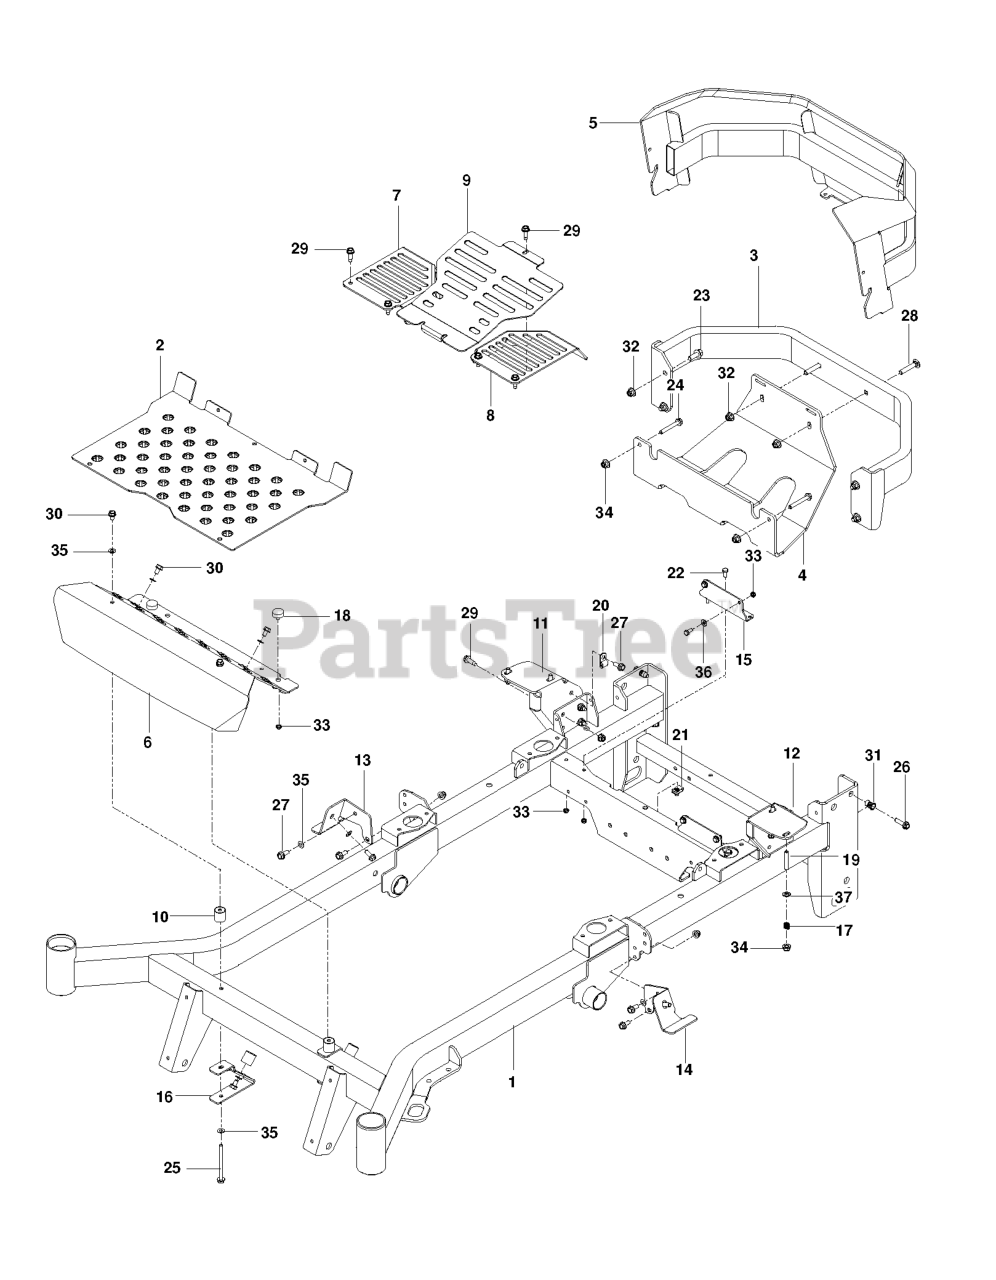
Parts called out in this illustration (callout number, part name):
1	FRAME W/DECALS, PZ
2	PLATE FLOOR PAN ORANGE
3	BUMPER, REAR, ORG
4	PLATE.SKID.GRAY
5	GUARD.ENGINE.GREY.498
6	PLATE, FOOT REST, OR
7	COVER, FAN RT BLK
8	COVER, FAN LT BLK
9	COVER, CENTER BLK
10	MOUNT, F/F INSERT
11	MOUNT, RT TANK, BLK
12	MOUNT, LT TANK, BLK
13	XX MOUNT, TANK, RT-BLK
14	MOUNT, TANK, LT-BLK
15	MOUNT TANK BLK
16	BRACKET, REST MOUNT
18	BUMPER, 1/4-20 STUD, 1/4
19	STUD, 5/16C
20	DOUBLE TUBE CLAMP
21	U-CLIP 5/16-18 NUT RETAINER
22	HCS 1/4C X 5/8
23	HHFS 3/8-16 X 1 GRD 5 ZD
24	HHFS 5/16-18 X 2.25 GD 5
25	HHFS 5/16-18 X 3 3/4
26	HHFS 5/16-18 X 1.25 TPBLT GD 5
27	HHFS 5/16-18 X 3/4
28	RHSNB 3/8C X 2
29	RP BLT 5/16-18 X 1 THRD FORM D
30	SCR 5/16-18 X 1/2 SELFTAP ZN
31	NUTSERT 5/16-18 THICK GRIP
32	NUT 3/8-16 HEX FLG NYLOC ZD
33	JAM NUT 1/4C (2 2 PW01)
34	5/16-18 NYLOC FLANGE NUT
35	WASH 5/16 DISC SPRING ZD
36	WASHER 1/4 SAE
37	WASHER
